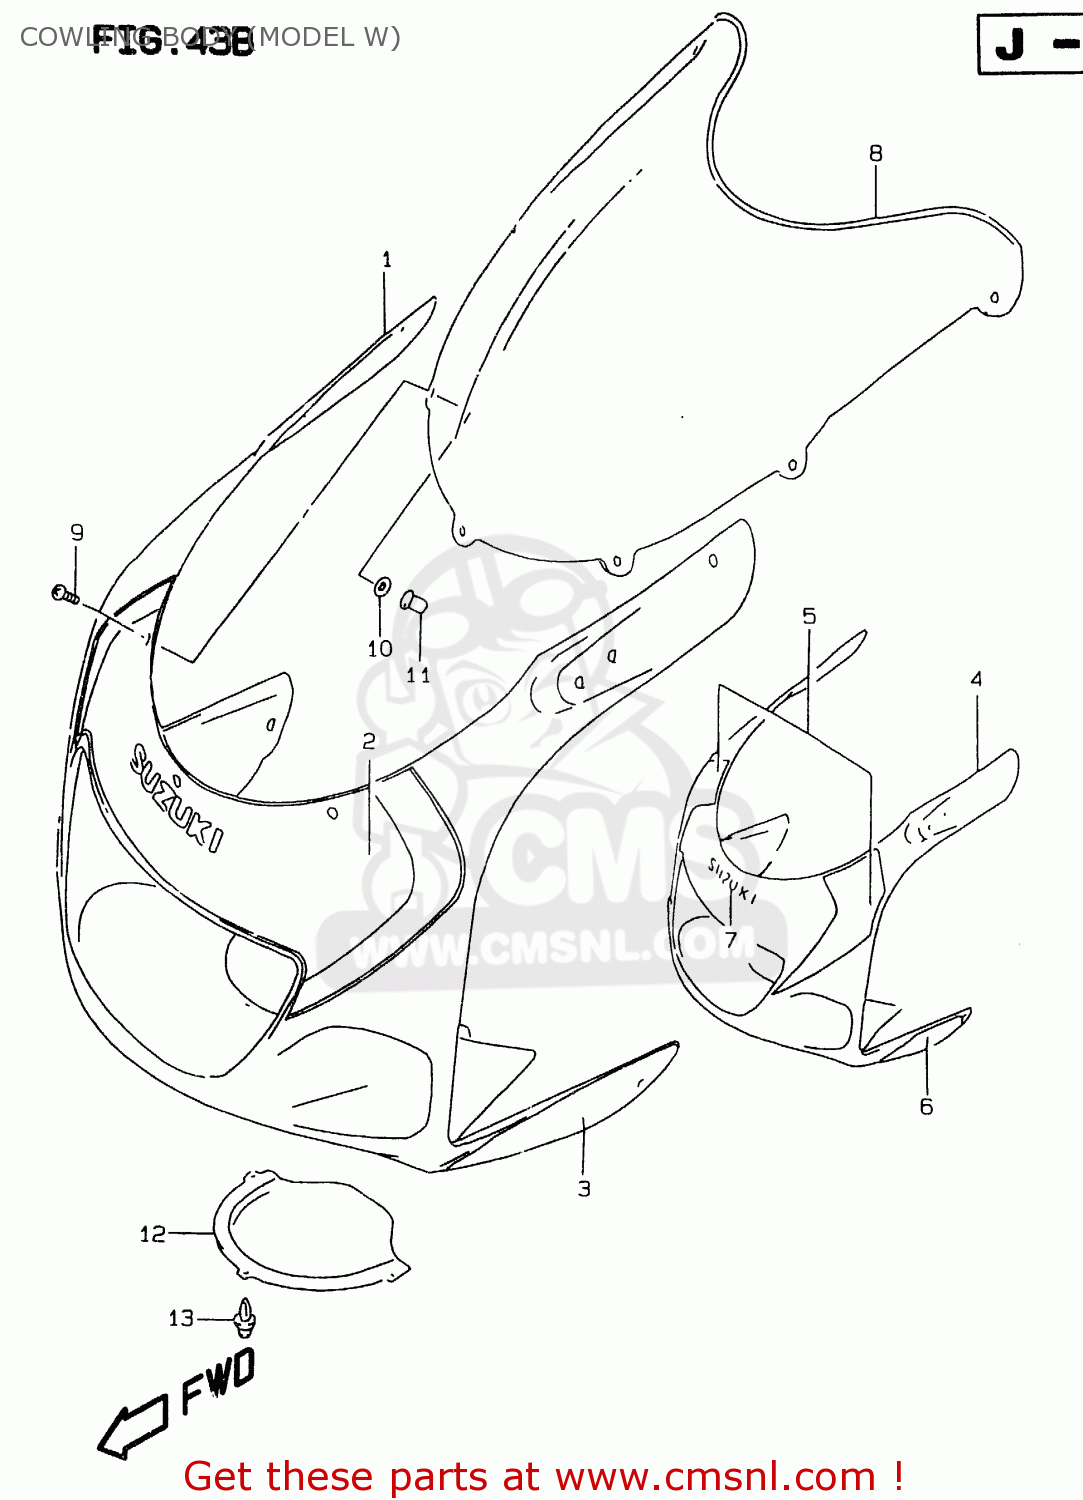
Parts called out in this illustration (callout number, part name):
1	COWLING ASSY,BODY
2	TAPE,COWL BODY FR
3	TAPE SET,COWL BODY SIDE
4	COWLING ASSEMBLY,BODY
5	TAPE SET,COWLING BODY
6	TAPE SET,COWL BODY SIDE
7	EMBLEM,SUZUKI
8	WINDSCREEN
9	SCREW(5X14)
10	WASHER
11	NUT
12	LID,BODY COWL LWR
13	CLIP(BLACK)
